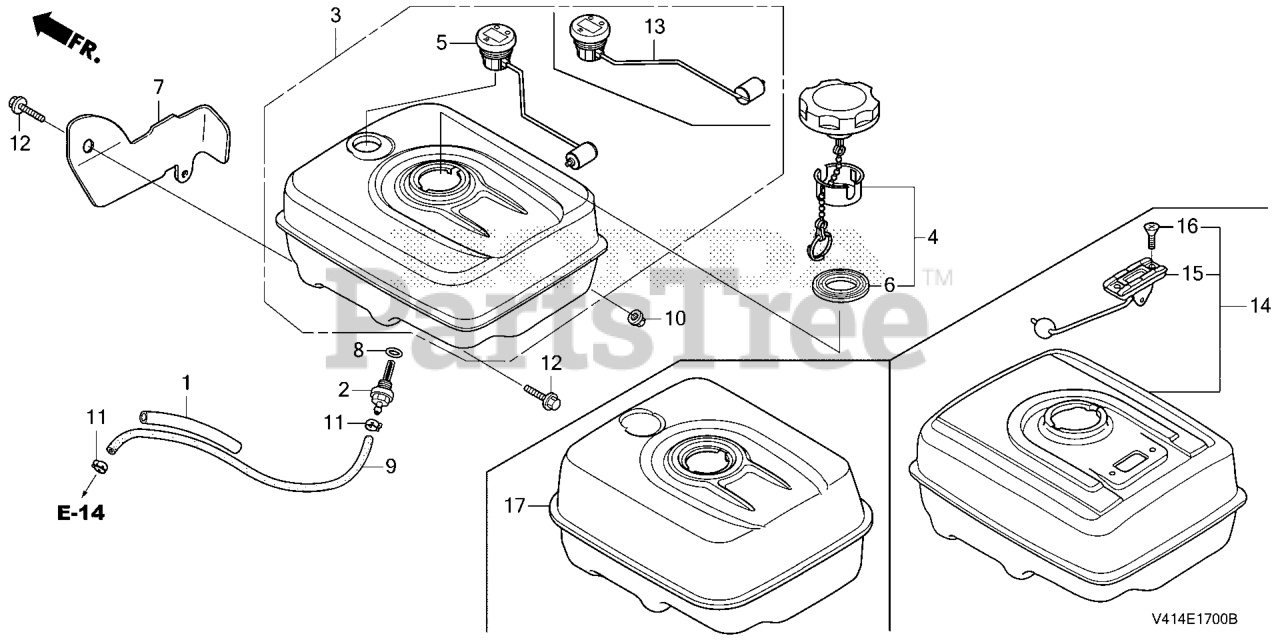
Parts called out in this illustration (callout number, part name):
1	RUBBER, SUPPORTER (107MM)
2	JOINT, FUEL TANK
4	CAP, FUEL FILLER
6	GASKET, FUEL FILLER CAP
7	COVER, SNOW PLATE
8	O-RING (14MM) (ARAI) Use up to Engine SN 2949254.
9	TUBE, FUEL (4.5X235) (FKM)
10	NUT, FLANGE (8MM)
11	CLIP, TUBE (D8)
12	BOLT, FLANGE (8X28)
17	TANK, FUEL *R280*
